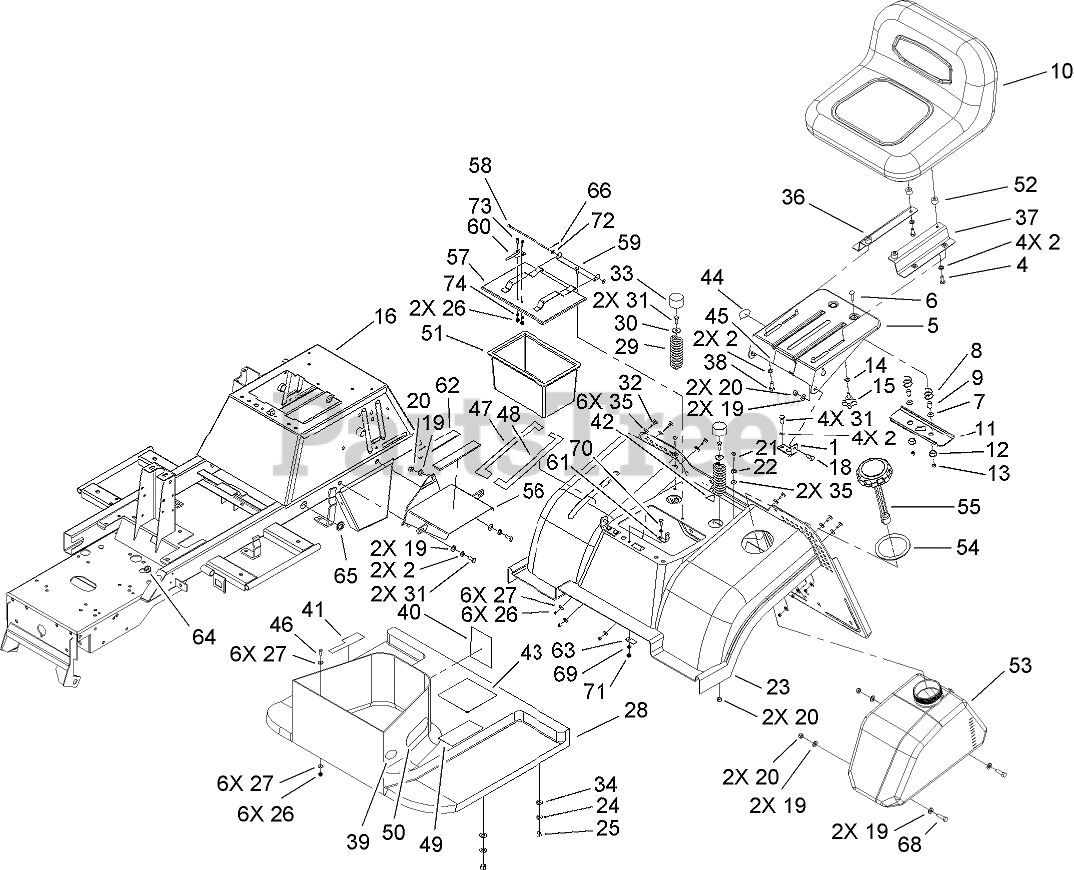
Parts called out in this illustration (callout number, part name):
1	BRACKET-SUPPORT, SEAT
2	WASHER-LOCK, SPRING
4	SCREW-HH
5	SUPPORT-SEAT
6	BOLT-CARRIAGE
7	WASHER-FLAT
8	SPRING-SEAT
9	SPACER-SPLIT
10	SEAT ASM
11	BRACKET
12	BUSHING
13	NUT-LOCK
14	WASHER-SPRING
15	KNOB-ADJUSTMENT
16	CHASSIS-FRAME
18	SCREW-SUPPORT, SEAT
19	WASHER-PLAIN
20	NUT-LOCK, NI
21	SCREW-HSFH
22	WASHER-FINISH
23	FENDER-REAR
24	WASHER-FLAT
25	NUT-LOCK, NI
26	NUT-LOCK
27	WASHER-FLAT
28	FOOTREST ASM
29	SPRING-SEAT
30	WASHER-PLAIN
31	SCREW-HH
32	BOLT-CARRIAGE
33	CAP-HUB
34	WASHER-RUBBER
35	WASHER-RUBBER
36	BRACKET-SEAT, RH
37	BRACKET-SEAT, LH
38	Screw
39	DECAL-BRAKE, PARKING
40	DECAL-STARTING
41	DECAL-OPERATION, HYDRO
42	DECAL-BAG TO FRAME
43	DECAL-INSTRUCTION
44	DECAL-SWITCH
45	DECAL-DANGER
46	SCREW-HH
47	DECAL-HOC, LH
48	DECAL-HOC, RH
49	DECAL-OPERATION
50	DECAL-TOWER
51	Box-Battery
52	SHIM-SEAT
53	TANK-FUEL
54	PROTECTOR-NECK, FILLER
55	CAP-FUEL
56	BRACKET-FUEL, TANK
57	COVER-STORAGE
58	HINGE-STORAGE, COVER
59	BRACKET-STORAGE, HINGE
60	LATCH-STORAGE, COVER
61	CATCH-STORAGE, LATCH
62	STRIP-RUBBER, FUEL TANK
63	SUPPORT-LATCH
64	GROMMET
65	GROMMET
66	PIN-COTTER
68	SCREW-HH
69	WASHER-FLAT
70	SCREW-HH
71	NUT-HEX
72	WASHER
74	WASHER
